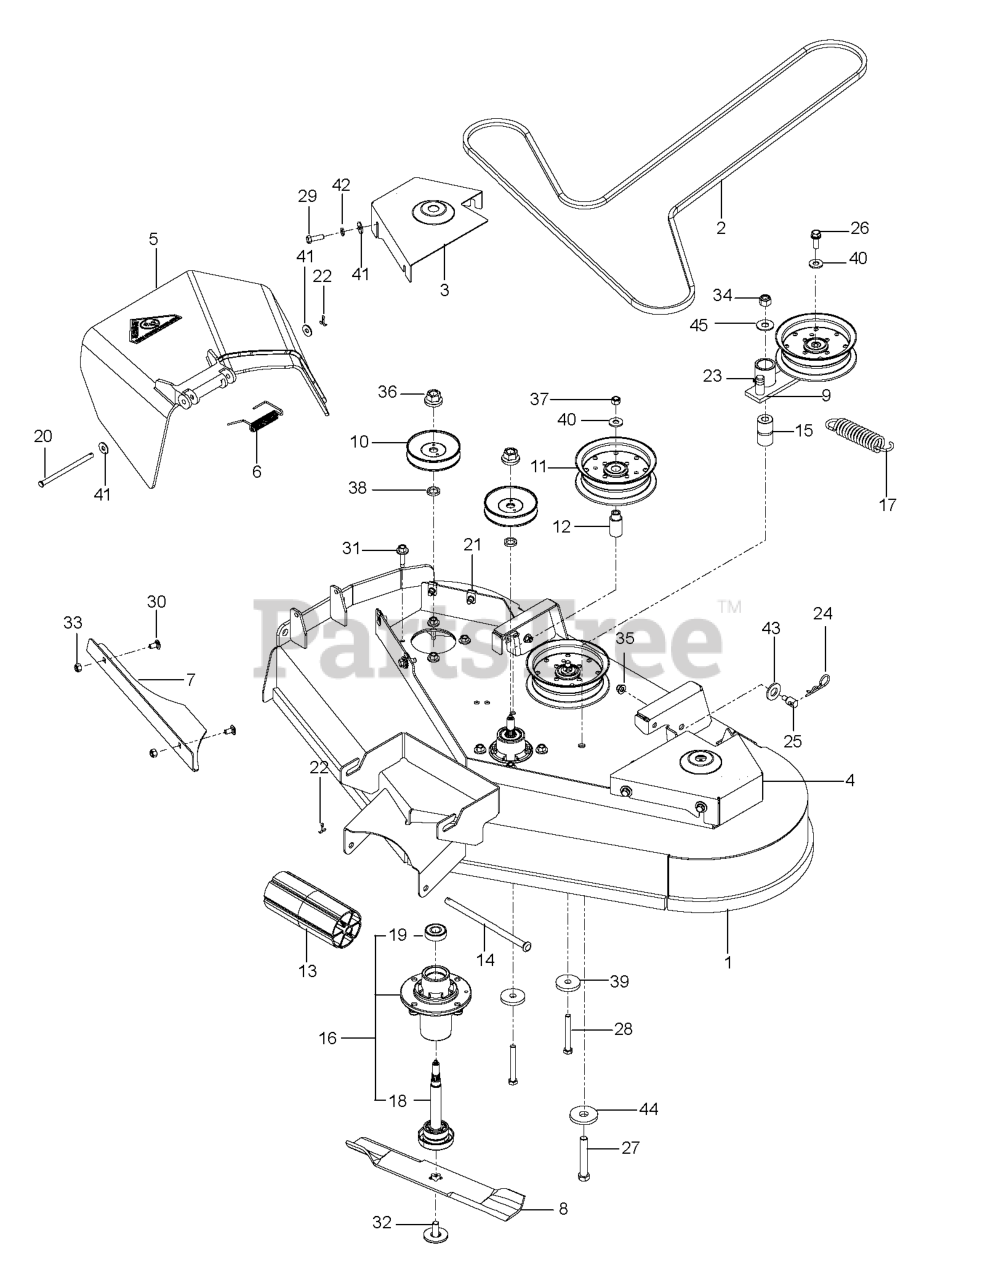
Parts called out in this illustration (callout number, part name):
1	DECK SVC W/DECALS 42 RZ ORANGE
3	BELT SHIELD, RIGHT 42, ORG
4	BELT SHIELD, LEFT 42, ORG
5	DISCHARGE CHUTE 42"
6	SPRING - TORSION
7	CONFINEMENT.PLATE.42".BLACK
8	BLADE, 14 5/8"
10	PULLEY, MADREL 3.70 OP
11	PULLEY, IDLER
12	IDLER BUSHING
13	NOSE ROLLER 48"
14	ROD.ROLLER.NOSE.NARROW.48"
15	PIVOT BUSHING
16	MANDREL.DECK.ASSEMBLY
18	GREASABLE MANDREL SHAFT
19	BEARING, BALL
20	PIN-CLEVIS 5/16 DIA X 5.19 ZD
21	U-CLIP 5/16-18 NUT RETAINER
22	RP_COTTER PIN 1/8 X 3/4
23	ZERK
24	HAIRPIN #4
25	STUD.FASTNER.W/ANTI-ROTATE
26	4CS 3/8C X 1 SERRATED HEAD
27	HCS 1/2C X 3 1/4
28	HCS 3/8C X 3
29	HCS 5/16C X 1
30	CARRIAGE BOLT 5/16C X 5/8"
31	WASHER HEAD SCREW
32	BLADE BOLT ASSY-7/16" TB REPL
33	NUT 5/16 NYLOC
34	NUT 1/2-13 HEX NYLOC ZD
35	5/16-18 NYLOC FLANGE NUT
36	LOCKNUT - 9/16
37	NUT 3/8-16 NYLOC
38	WASHER-SPACER
39	SPINDLE WASHER
40	WASHER 3/8 FLAT
41	WASHER 5/16 FLAT
42	WASHER.LOCK.HVY.HLCL.SPR.5/16
43	WASHER 5/8 FLAT
44	WASHER, SUPPORT
45	WASHER 1/2 FLAT
